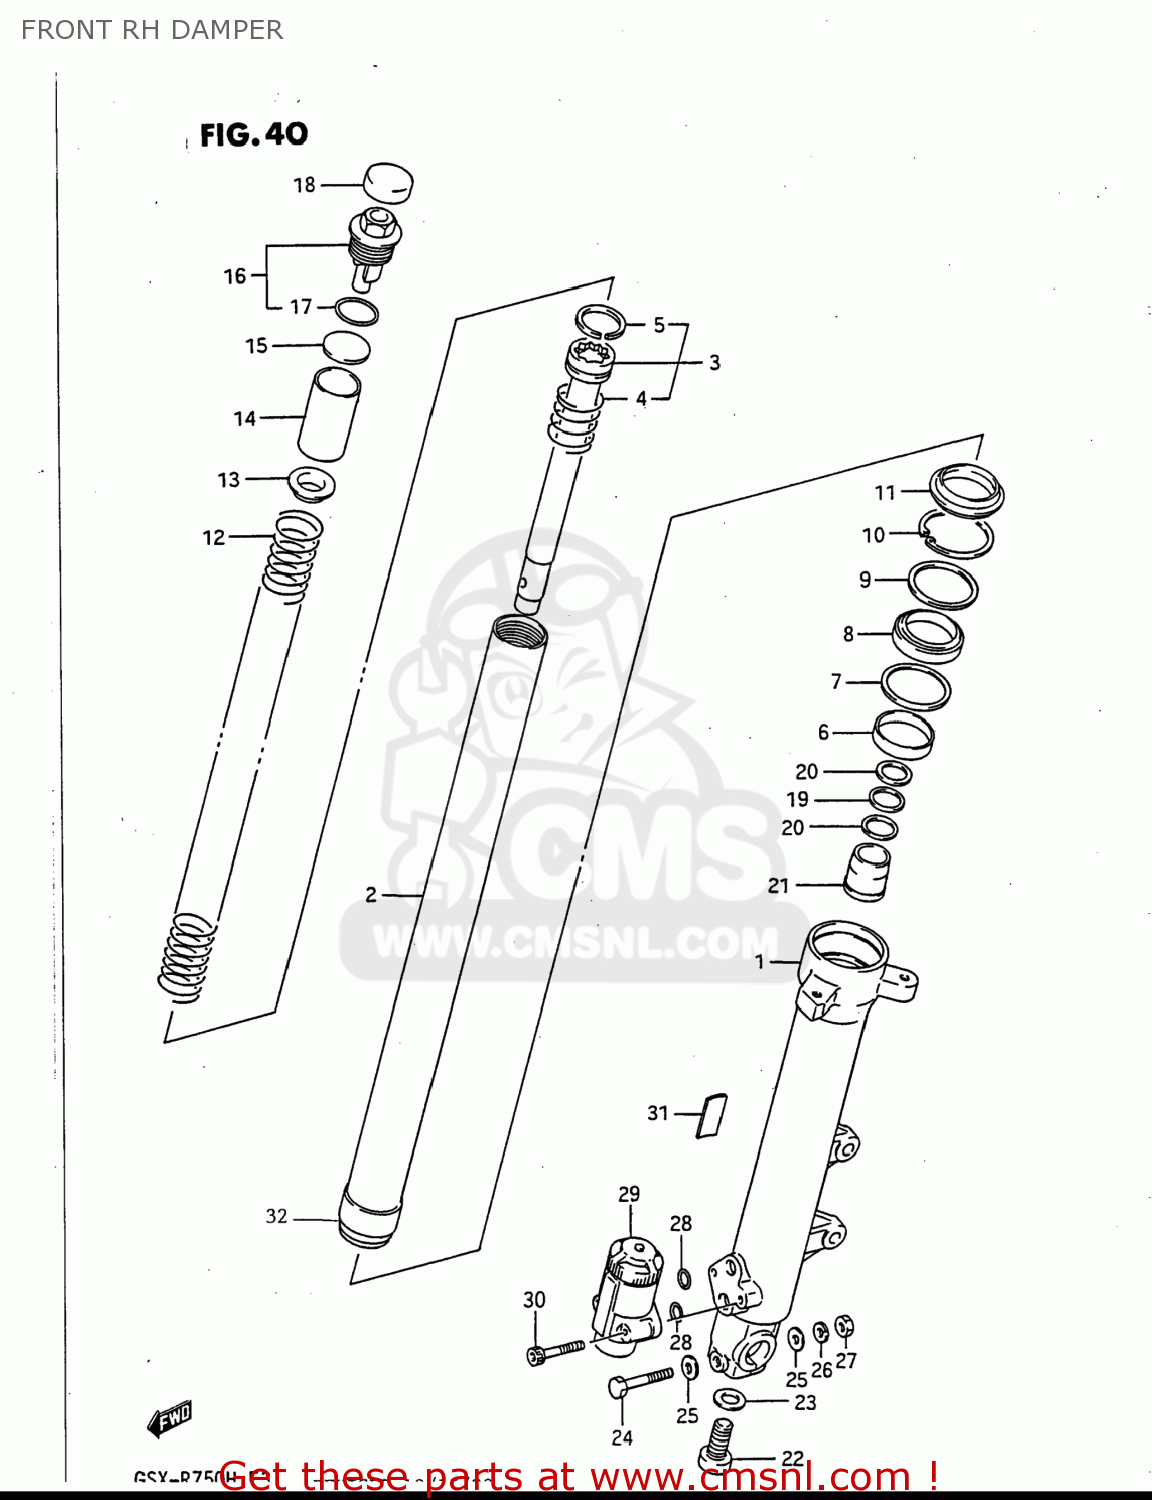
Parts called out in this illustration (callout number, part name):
1	TUBE,OUTER,RIGHT
2	TUBE,FORK INNER
3	CYLINDER,FRONT FORK
4	SPRING,FORK REBOUND
5	RING,FR FORK PISTON
6	METAL,SLIDE
7	WASHER,FORK OIL SEAL
8	OIL SEAL,FRONT FORK
9	WASHER,FORK OIL SEAL
10	RING,OIL SEAL STOPPER
11	DUST SEAL,FRONT FORK
12	SPRING,FRONT FORK
13	WASHER
14	SPACER
15	WASHER,FR FORK SPRING
16	CAP,FORK INNER TUBE
17	O RING
18	CAP,FORK INNER TUBE
19	WASHER,OIL LOCK PIECE
20	SPRING,FORK OIL LOCK PIECE
21	PIECE,OIL LOCK
22	BOLT(14X25)
23	GASKET (NAS)
24	BOLT 8X55
25	WASHER
26	WASHER,LOCK
27	NUT
28	O RING
29	PDF ASSEMBLY
30	BOLT
31	EMBLEM
